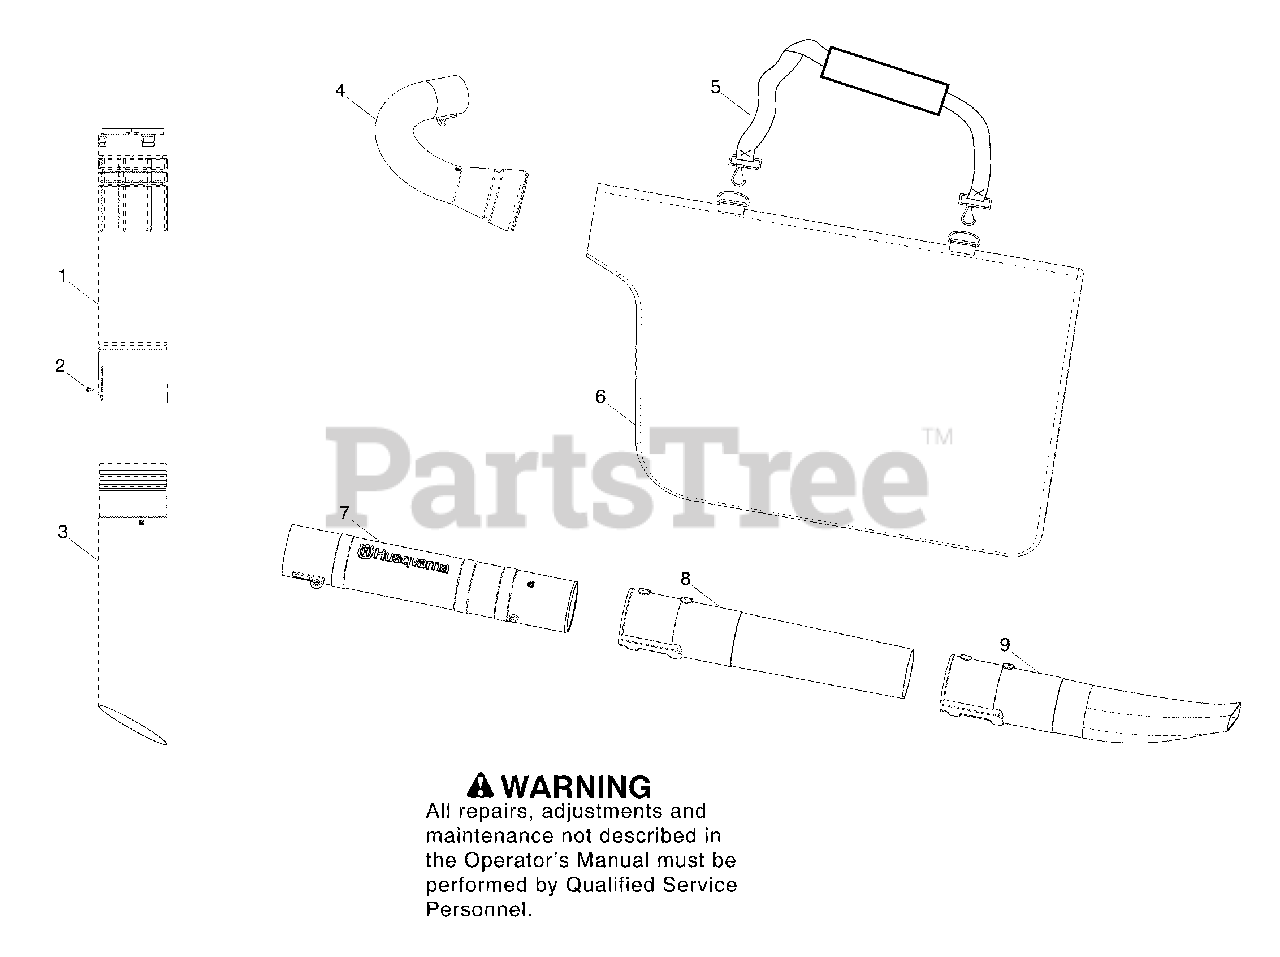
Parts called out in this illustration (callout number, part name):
1	Assy - Upper vac tube with adapter
3	Tube - Lower vac
4	Elbow - Vac
5	Strap - Carrying
6	Assy - Vac bag
7	Assy - Tube - upper blower w/barrier
8	Tube - Lower blower
9	Tube - Lower blower
